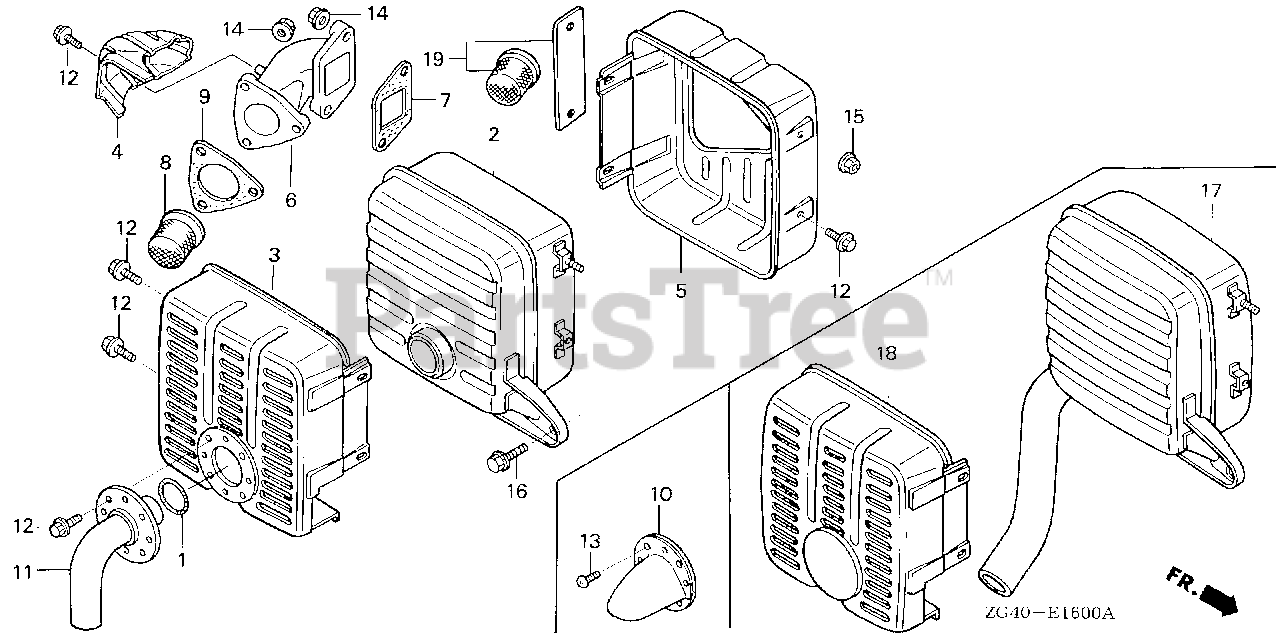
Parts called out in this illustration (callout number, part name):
3	PROTECTOR A, MUFFLER
4	PROTECTOR, EX. PIPE
5	PROTECTOR B, MUFFLER
6	PIPE, EX.
7	GASKET, EX. PIPE (NON-ASBESTOS)
8	ARRESTER, SPARK
9	GASKET, MUFFLER (NON-ASBESTOS)
10	DEFLECTOR, MUFFLER
12	BOLT, FLANGE (5X8)
13	SCREW, PAN (5X8)
14	NUT, FLANGE (8MM)
15	NUT, FLANGE (8MM)
16	BOLT, FLANGE (8X20)
